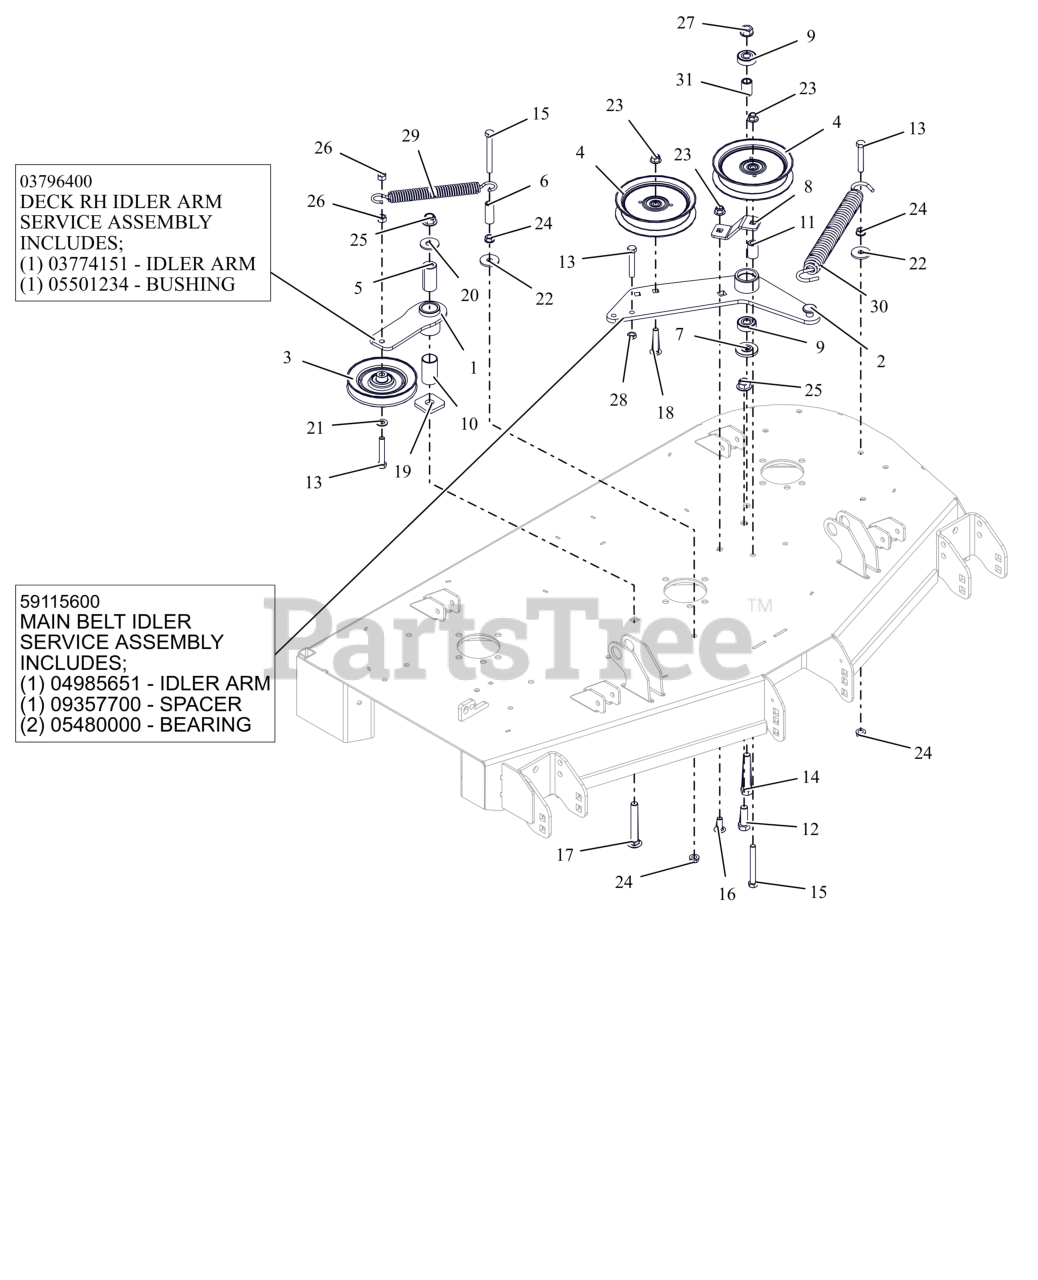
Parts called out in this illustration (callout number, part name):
1	WMT, IDLER ARM - BLACK
1	ASM, IDLER ARM (DECK)
2	DECK PTO IDLER ARM WLDMT - BLK
2	ASSEMBLY, MAIN BELT IDLER
3	IDLER, V-5.00"
4	IDLER, FLAT 5.00"
5	BSHG, SPCR .502X.997X2.03 PM
6	SPACER, .375IDX.625ODX1.66 PM
7	SPACER, IDLER ARM
8	PTO FIXED IDLER MTG BRKT-ORG
9	BRG-BALL .500X1.38X.437
10	BSHG, 1.00X1.125X1.937
11	BUSHING, SLV .380X.750X1.190
12	BLT,HEX .50-13X1.50 G5 ZCC
13	BLT,HEX .38-16X2.25 G5 ZCC
14	BLT, HEX .50-13X3.00 G5 ZCC
15	BLT, HEX .38-16X3.25 G5 ZCC
16	BLT,RHSSN .38-16X1.00 G5 ZCC
17	BLT, RHSN .50-13X3.50 G5 ZCC
18	BLT,RHSSN.375-16X2.00 G5 ZCC
19	WSHR-FLT .640X1.75X.250
20	WSHR,FLT .563X1.375X.109 ZCC
21	WSHR,FLT .406X.812X.065 ZCC
22	WSHR,FLT .406X1.375X.135 ZCC
23	NUT,NYL-FLG .38-16 GF ZCC
24	NUT, SPNLK-FLG .38-16 G5 ZCC
25	NUT,NYL-FLG .50-13 GF ZCC
26	NUT-LK-CTR .38-16 ZC120
27	NUT-LK-CTR-FLG .500-13 GG ZCC
28	NUT-JAM .375-16 G2 ZCC
29	SPRING, EXTENSION
30	SPRING, EXTENSION
31	SPACER .510 X .75 X 1.1485
